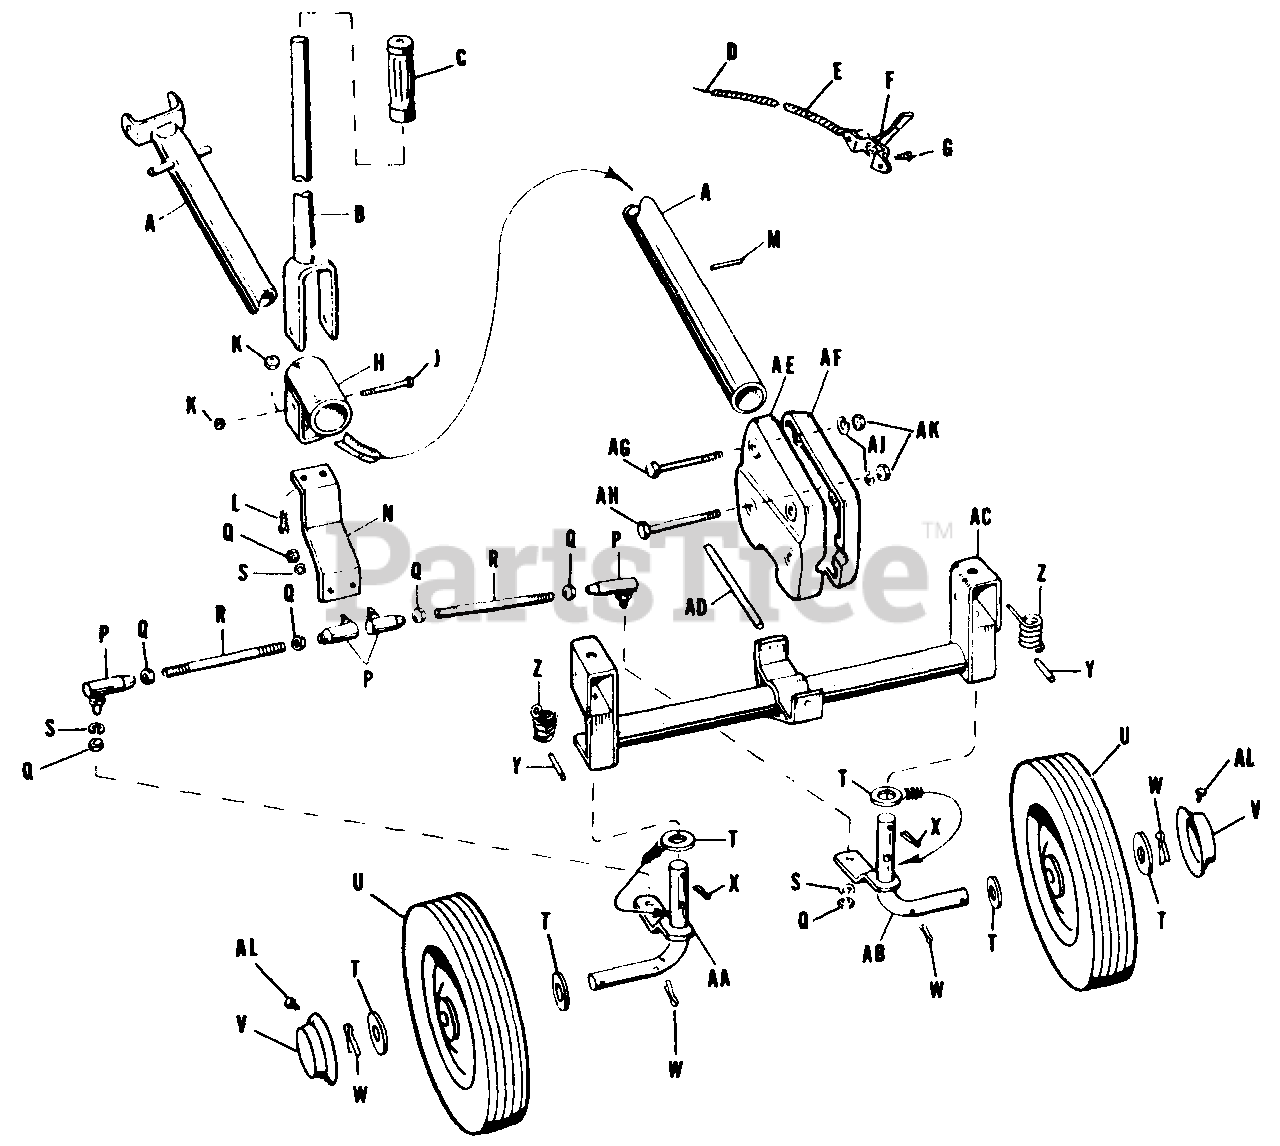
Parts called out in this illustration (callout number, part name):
A	Frame Assembly, Front
B	Handle Assembly
C	Grip, Handle
D	Wire, Throttle
E	Cable, Throttle
F	Control, Throttle Lever
G	Screw, Rd. Hd., Self Tapping, #10-24 x 1/2
H	Pivot Assembly, Steering
J	Screw, Hex Hd. Cap, 3/8-16 x 3 1/4
K	Lock Nut, Hex, 3/8-16
L	Screw, Hex Cap, 3/8-16 x 7/8
M	Pin, Roll, 7/32 x 1" Long
N	Arm, Lever
P	Joint, Ball
Q	Nut, Full Hex, 3/8-24
S	Lock Washer, 3/8
U	Wheel & Tire Assembly, Front
V	Hub Cap, Front
W	Pin, Cotter, 3/16 x 1 1/4
X	Pin, Cotter, 5/32 x 1
Y	Pin, Roll, 5/16 x 1 1/4
Z	Spring, Torsion
AA	Spindle Assembly, R.H.
AB	Spindle Assembly, L.H.
AC	Axle Assembly, Front
AD	Pin, Pivot
AE	Support, Front, R.H.
AF	Support, Front, L.H.
AG	Screw, Hex Cap, 3/8-16 x 3 1/4
AH	Screw, Hex Cap, 3/8-16 x 3 3/4
AJ	Lock Washer, 3/8
AK	Nut, Full Hex, 3/8-16
AL	Screw, Self Tapping #10 x 1/2 long
